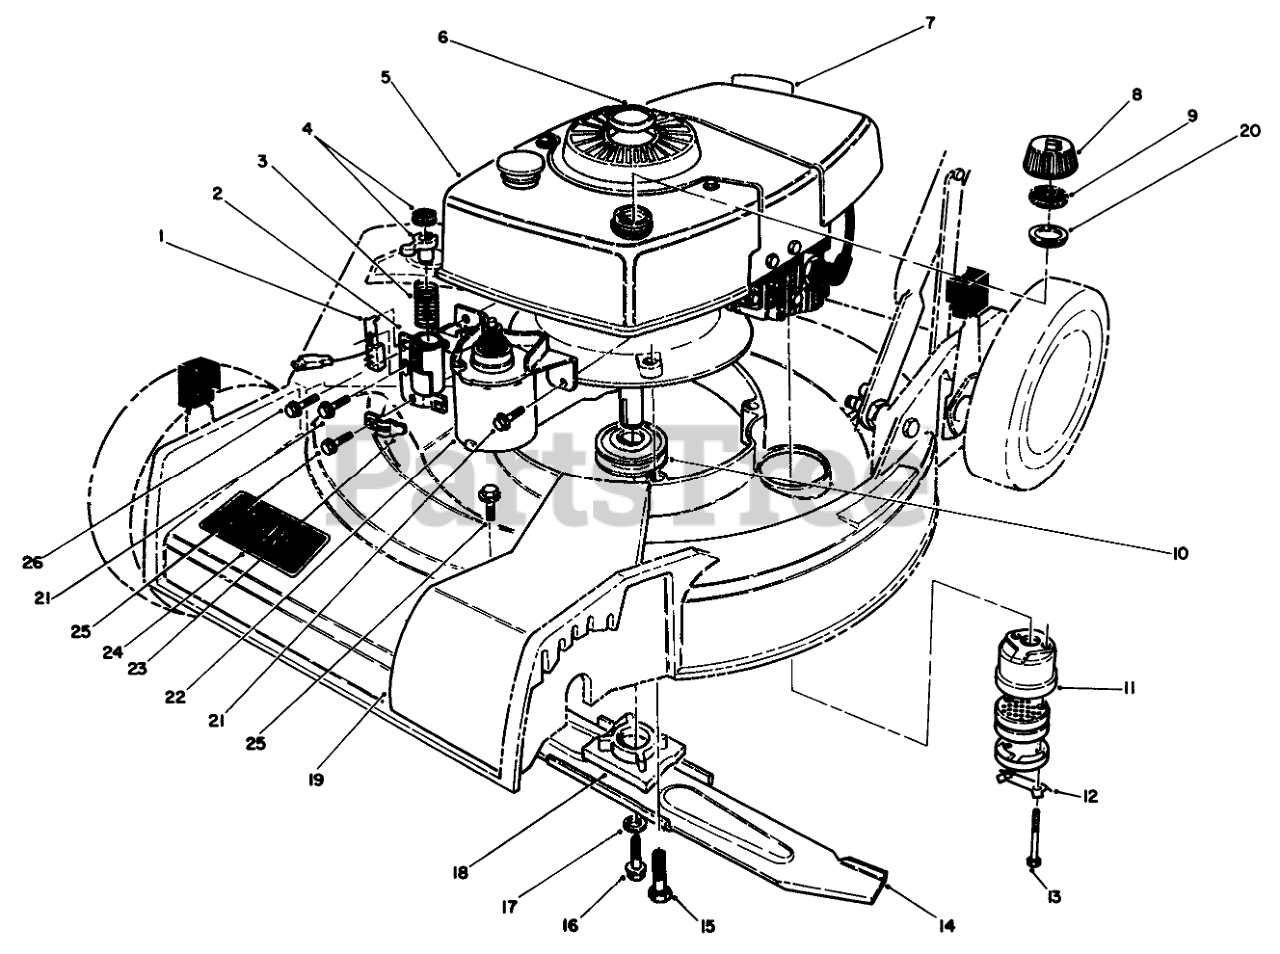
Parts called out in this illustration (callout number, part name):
1	PUSH BUTTON SWITCH
2	TUBE W A
3	COMPRESSION SPRING
4	BRAKE PAD/PLUNGER ASM
6	PLUG BUTTON
7	Decal-Maintenan
8	Gas Cap Assembly (Incl. Ref. #9 & 20)
9	GASKET
10	PULLEY-DRIVER
11	Muffler Assembly (Incl. Ref. #12 & 13)
12	CLIP - LOCKING
13	SCREW-HH
14	Blade
15	3/8-16 X 2-3/4 CAPSCR
16	SCREW-HH
17	WASHER-LOCK
18	BLADE RETAINER
19	BELT COVER 21" S D
20	GAS CAP BAFFLE
21	SCREW
22	STARTER MOTOR ASM
23	CABLE CLAMP
24	DECAL
25	SCREW
26	Screw
